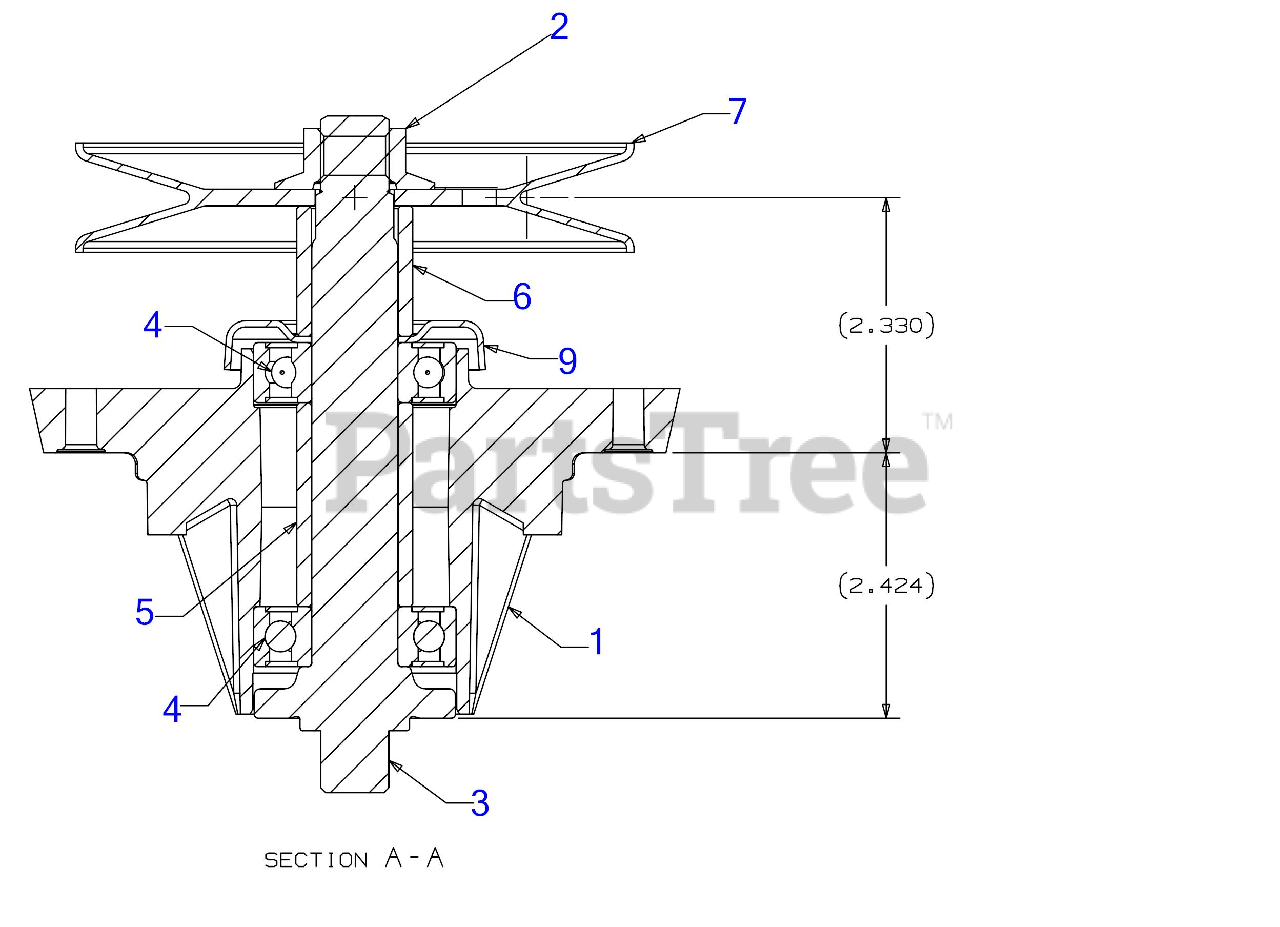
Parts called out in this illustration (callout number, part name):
1	DECK SPINDLE HOUSING
2	FLANGE NUT 5/8-18
3	BLADE SPINDLE SHAFT
4	BALL BEARING
5	SPACER .792 x 1.060 x 1.860
6	SPACER .792 x 1.060 x 1.191
7	SPINDLE PULLEY 5.2 DIA
9	SHIELD-BRG DECK
